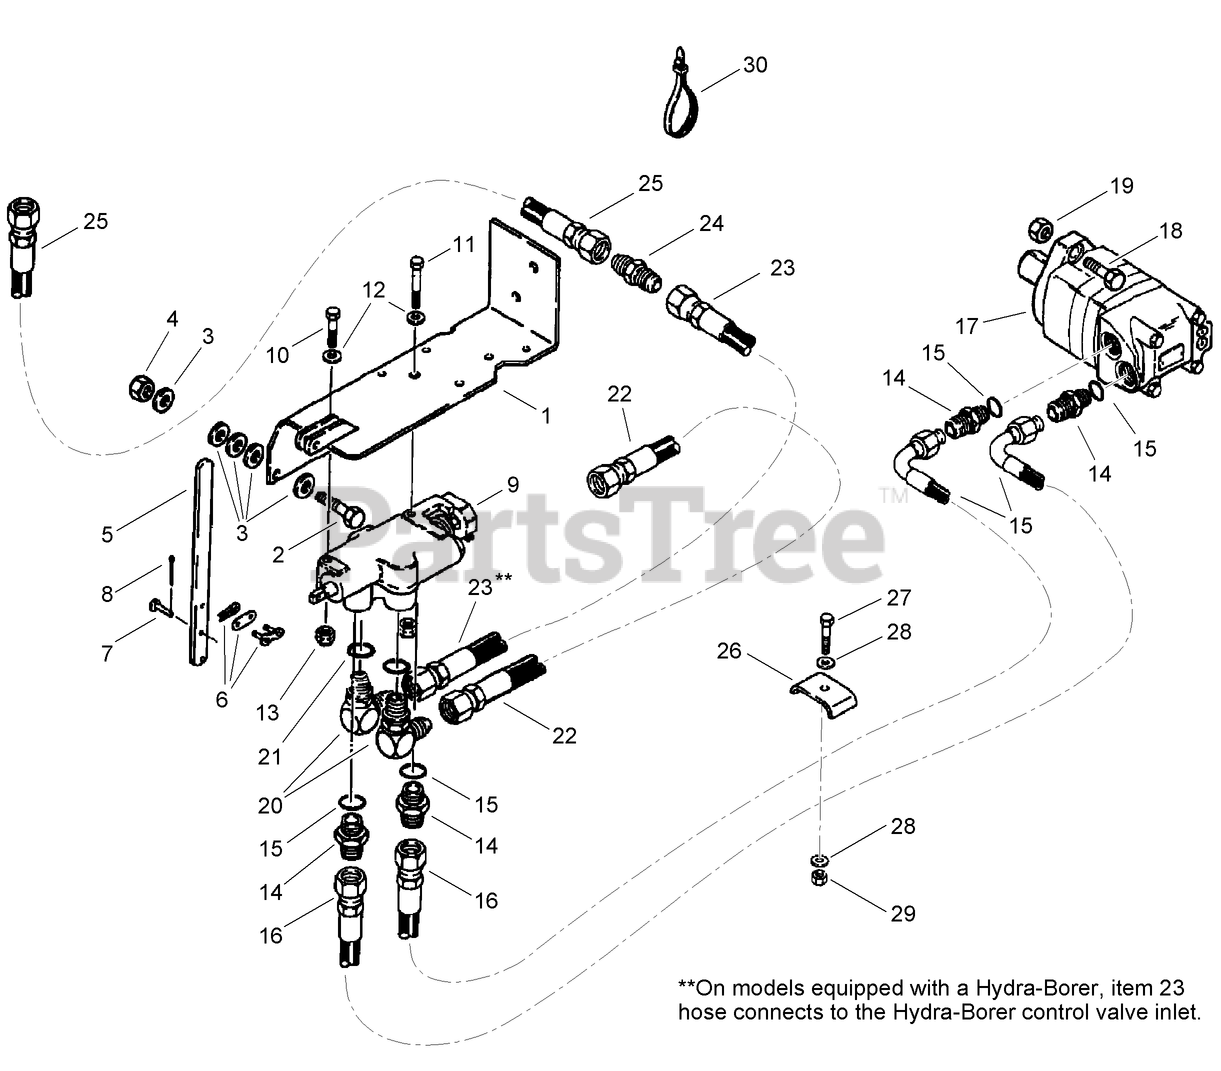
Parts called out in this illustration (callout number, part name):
1	BRACKET - Switch and Valve Mounting
2	SCREW-HH
3	WASHER-0.406 x 0.812 x 0.065 in CST ZND
4	NUT-HEX
5	LEVER-VALVE
6	LINK-#50, CONNECT (SINGLE PITCH)
7	PIN-CLEVIS
8	PIN - Cotter .062 x .50 in ZND
9	HYD VALVE ASM
10	BOLT-Hex Hd 5/16 x 2-1/4
12	WASHER-FLAT
13	NUT-HEX
14	CONNECTOR-Str Thd 5/8, 37FL-ORB 5/8
15	O-RING
16	HOSE - 2100 mm (82-11/16 inch) Long, 2100 mm Long, Control Valve to Trencher Drive Motor
17	HYD MOTOR ASM
18	SCREW-HH
19	NUT-LOCK, HEX
20	ELBOW-90 Adj 37FL 5/8 Tube
21	O-RING
22	HOSE - 940 mm (37 inch) Long (940 mm) Long, Trencher Control Valve Supply from Plow Double Pump
23	HOSE - 400 mm (15-3/4 inch) Long (400 mm) Long, Trencher Control Valve Outlet to Plow Control Valve
24	FITTING-UNION
25	HOSE - 5/8 x 1600
27	BOLT-hex, 5/16 NC x 1-3/4 inch
28	WASHER-FLAT
29	NUT-HEX
30	STRAP - Tie, 15 inch, Nylon, Retaining
